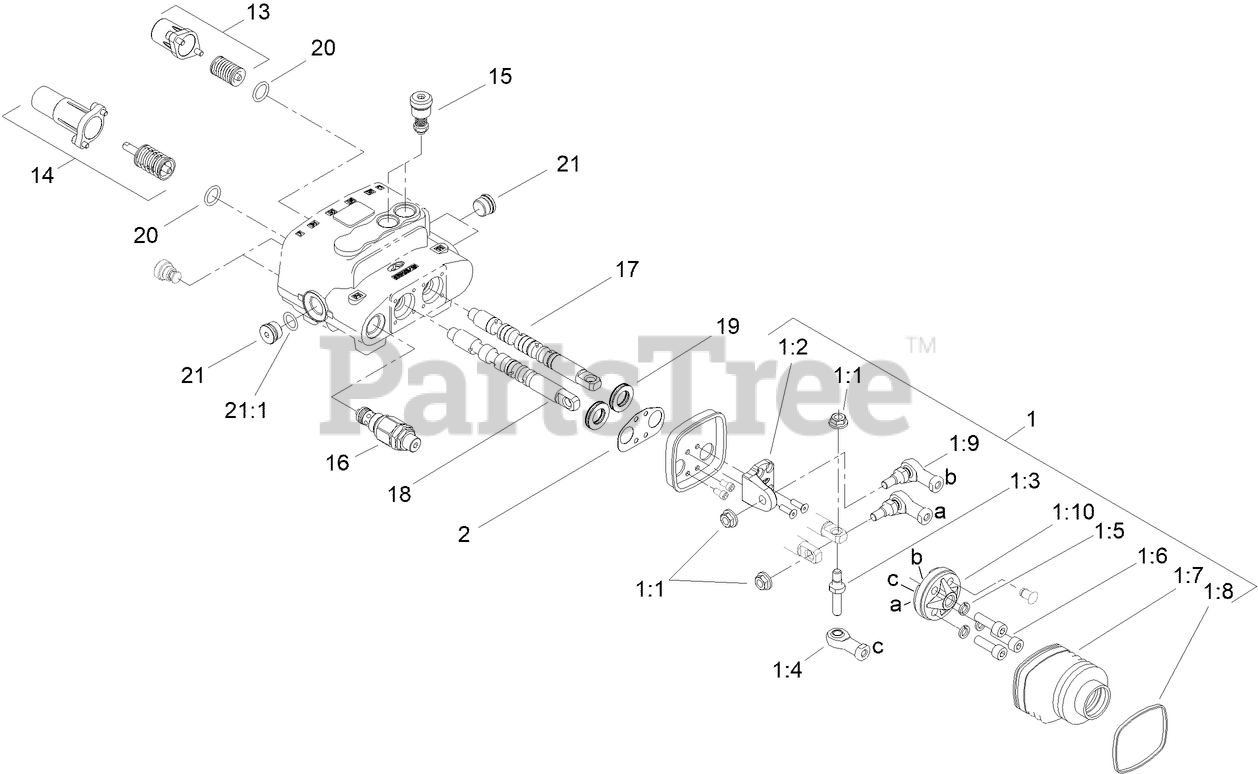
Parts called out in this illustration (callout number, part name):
1	JOYSTICK KIT
1:2	PIVOT-JOYSTICK
1:3	PIN-JOYSTICK
1:4	END-ROD
1:6	SCREW-HSH
1:7	BELLOW-RUBBER
1:8	TIE-CABLE
1:9	JOINT-JOYSTICK
1:10	HOLDER-ARTICULATED
2	SEAL-JOYSTICK
13	VALVE SPRING KIT
14	DETENT SPRING KIT
15	VALVE-RELIEF
16	VALVE-RELIEF, MAIN
17	SPOOL-VALVE
18	SPOOL - VALVE
19	SEAL-VALVE, SPOOL
20	SEAL-VALVE
21	PLUG-HEX
21:1	O-RING
